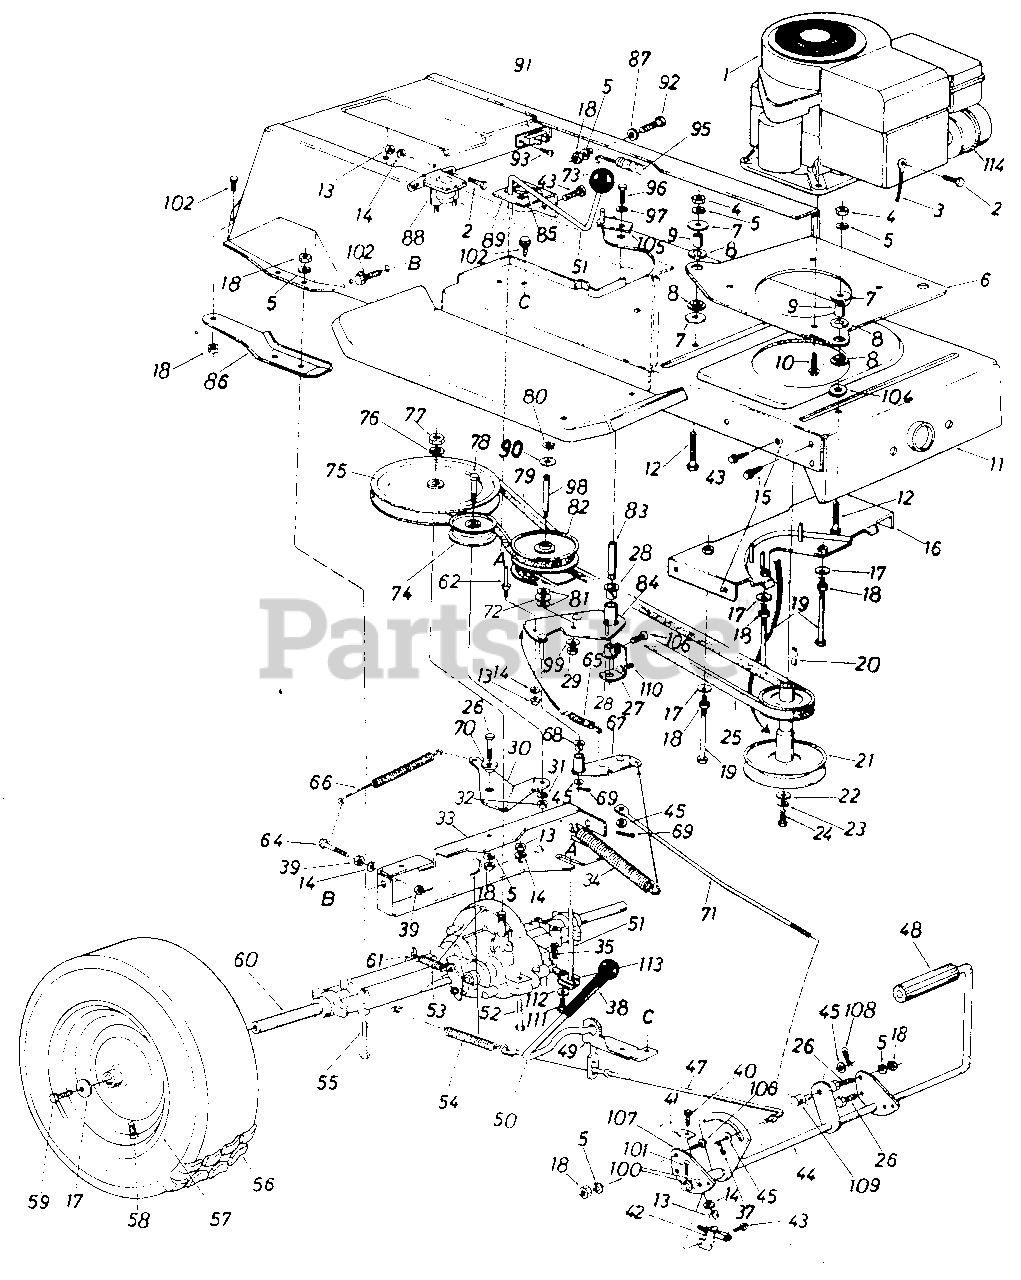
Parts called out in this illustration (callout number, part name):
1	Engine
2	Hex Bolt 1/4-20 x .62" Lg.
3	Electric Ground Wire
4	Hex Nut 5/16-24 Thd.
5	L-Wash. 5/16" I.D.
6	Engine Mounting Plate
7	Fl-Wash. .320" I.D. x 1.25"
8	Engine Mounting Grommet
9	Spacer
10	Hex Bolt 3/8-16 x 1.25" Lg.
11	Lower Frame Ass'y.
12	Hex Bolt 5/16-24 x 1.25"
13	Hex Nut 1/4-20 Thd.
14	L-Wash. 1/4" I.D.
15	Hex Wash. Hd. AB-Tap Scr. 5/16" x.75" Lg.
16	Belt Guard Brkt. Ass'y.
17	Bell-Wash. .345" I.D. x .88"
18	Hex Nut 5/16-18 Thd.
19	Hex Bolt 5/16-18 x 5.25" Lg.
20	Sq. Key 1/4" x 1/4" x 2.00"
21	Engine Pulley
22	Fl-Wash. 7/16" I.D. x 1.25"
23	L-Wash. 7/16" I.D.
24	Hex Bolt 7/16-20 x 1.50" Lg.
25	Variable-Speed Belt
27	Bearing Shaft Bracket Ass'y.
28	Flanged Nyliner Brg. 5/8" I.D. x .88" Lg.
29	Hex Nut 3/8-24 Thd.
30	Idler Bracket
31	L-Wash. 3/8" I.D.
32	Hex Nut 3/8-24 Thd.
33	Transaxle Support Brkt.
34	Ext. Spring .94" O.D. x 6.7
35	Inter. Cott-Pin
37	Cotter Pin 3/32" Dia. x .75"
38	Grip Black
39	Hex Nut 1/4-28 Thd.
40	Hex Bolt 1/4-20 x 1.00" Lg.
41	Switch Actuator
42	Safety Switch
43	Hex Wash. Hd. S-Tap Scr. 1/4-20 x .50" Lg.
44	Clutch/Brake Pedal Ass'y.
45	Fl-Wash.
47	Brake Rod 20.9" Lg.
48	Foot Pad
49	Brake Lever Bracket
50	Hill Holder Brake Handle
51	Shift Lever Ass'y.
52	Hex Bolt 1/4-28 x 1.75" Lg.
53	Ext. Spring .38" O.D. x 2.5"
54	Ext. Spring .59" O.D. x 7.08"
55	Hex Bolt 5/16-18 x 2.75"
56	Wheel Ass'y. Comp.
57	Wheel Rim Only
58	Air Valve
59	Hex Bolt 5/16-24 x .75" Lg.
60	Transaxle Complete
61	Brake Return Spring Anchor
62	Belt Guard Pin 1/4-20 Thd.
64	Hex Bolt 1/4-28 x 1.25" Lg.
65	Ext. Spring
66	Ext. Spring .62" O.D. x 6.12"
67	Variable Speed Torque Brkt. Ass'y.
68	Flanged Bearing
69	Cotter Pin 3/32" Dia.
70	Shoulder Spacer .27" Lg.
71	Speed Control Link
72	Truss Bearing .56 Dia. x 1 .25"
73	Ball Knob
74	Fl-Idler Pulley 3.25" x 1.0"
75	1/2" "V"-Pulley 8.0" O.D. x .501 " I.D.
76	L-Wash. 1/2" I.D.
77	Hex Jam Nut 1/2-20 Thd.
78	Hex Bolt 3/8-24 x .75" Lg.
79	Variable Speed Belt
80	Snap Ring .56" Dia.
81	Fl-Wash.
82	Variable Speed Pulley Ass'y. 5" O.D.
83	Bearing Shaft
84	Variable Speed Brkt. Ass'y.
85	Comp. Spring Clip
86	Transaxle Support Brkt. R.H.
87	Fl-Wash. .34 I.D. x 1.12 O.D.
88	Solenoid
89	Shift Lever Bracket
90	Teflon Washer
91	Circuit Breaker
92	Hex Bolt 5/16-18 x 1.50" Lg.
93	Truss Hd. Phil. Scr. #10 x 1/2 " Lg.
95	Ext. Spring .99" O.D. x 11"
96	Hex Bolt 3/8-24 x .75" Lg.
97	Bell-Wash. .38" I.D. x .88"
98	Shaft .56" Dia. x 3.875" Lg.
99	Bell-Wash. .39" I.D. x 1.12"
100	Fl-Wash.
101	Cotter Pin 3/32" Dia. x 1.0"
102	Hex Wash. Hd. Scr. 5/16-18 x.62" Lg.
104	Fl-Wash. .32" I.D. x 1.25"
105	Belt Guard
106	Truss Mach. Scr. 5/16-18 x .75" Lg.
107	Pedal Bracket
108	Cotter Pin 3/32" Dia. x .75"
109	Ferrule
110	Truss Phillips Hd. Scr. 5/16-18 x 1.0" Lg.
111	Hex Bolt 1/4-28 x .50" Lg.
112	Bell-Wash. .265" I.D. x .75"
113	Shift Lever Link Ass'y.
114	Muffler
